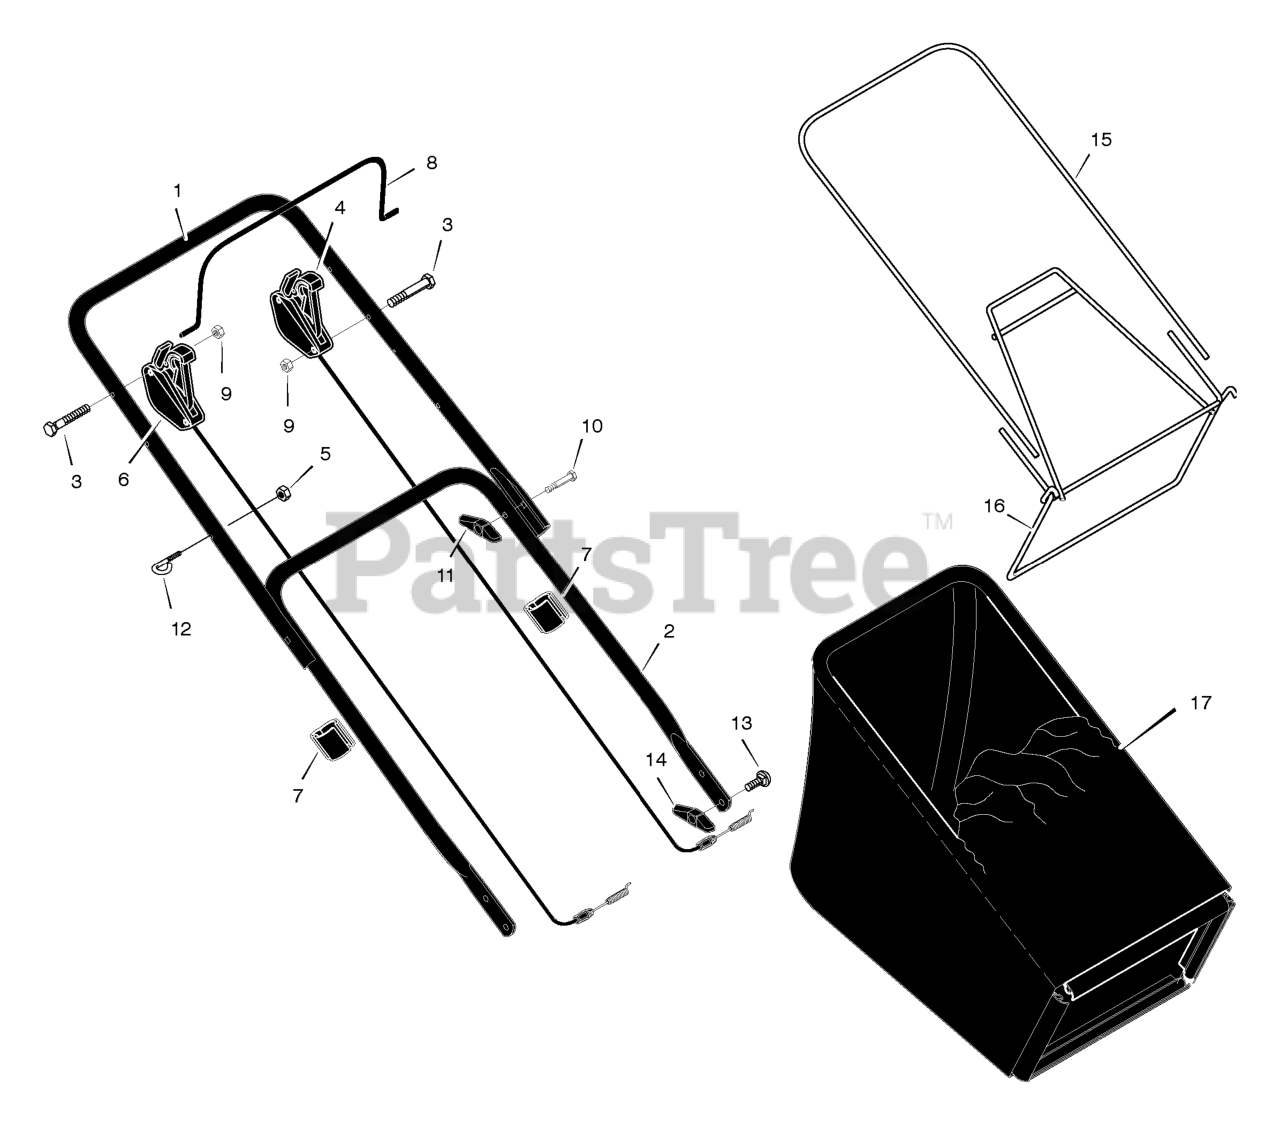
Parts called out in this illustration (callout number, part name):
1	Handle, Upper
2	Handle, Lower
4	Control, Drive
5	Locknut
6	Control, Starter
7	Fastener, Cable
8	Lever, Stop
11	Knob
12	Guide, Rope
13	Bolt, Carriage
14	Knob, Plastic
15	Tube, Bag
16	Frame Assembly
17	Bag, Cloth
